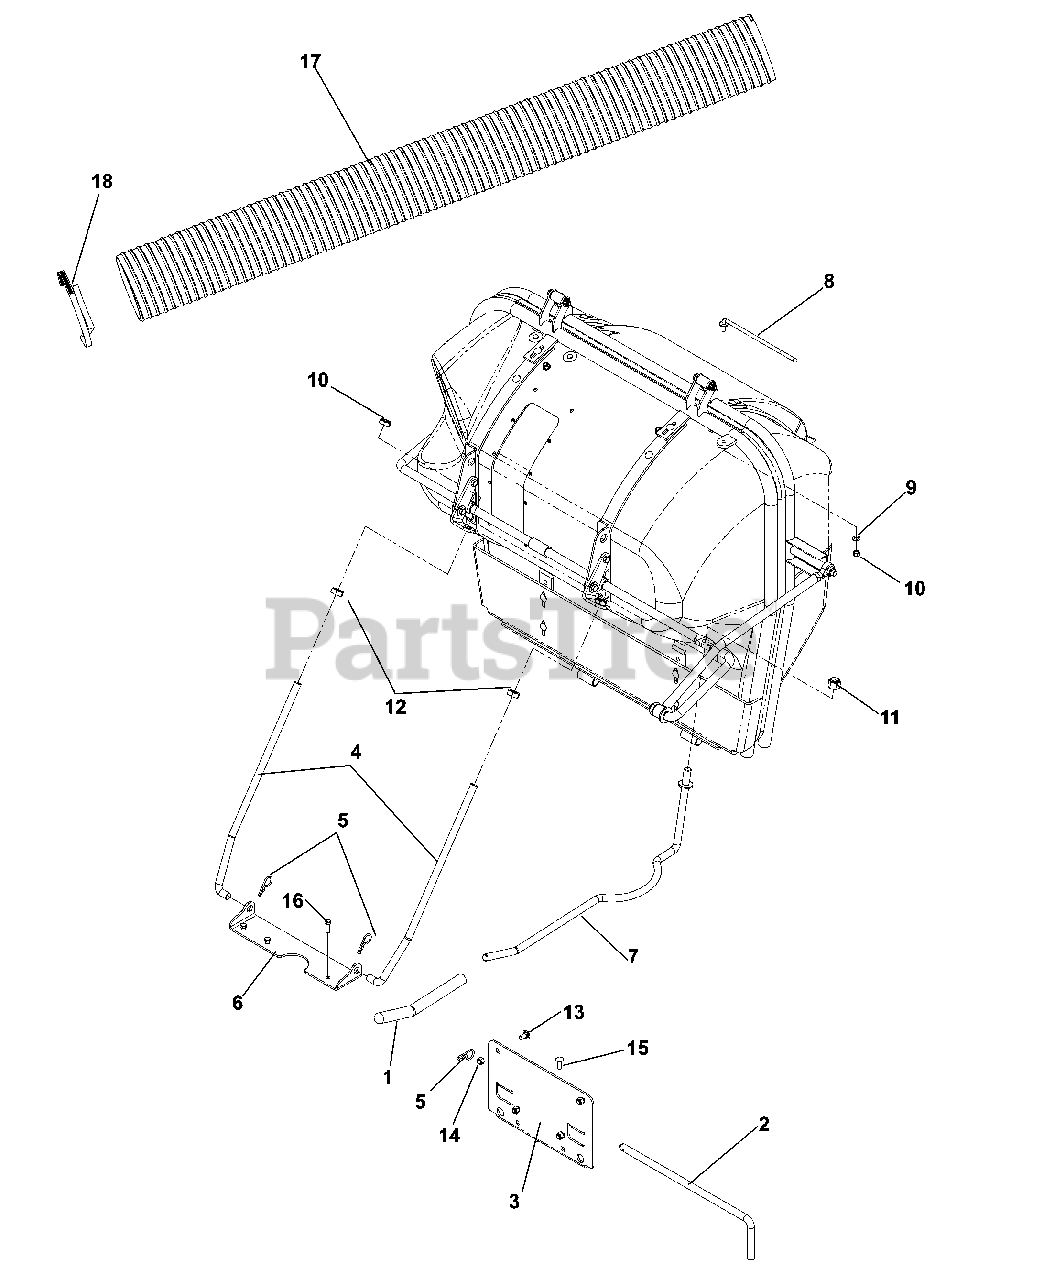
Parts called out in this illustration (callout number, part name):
1	BAR SLEEVE
2	HINGE PIN
3	BRACKET, MOUNT, LOWER
4	LINKAGE, SUPPORT
5	PIN, COTTER 1 3/4
6	BRACKET, SUPPORT, LINKAGE
7	LINKAGE, ARM, DUMP
8	LINKAGE.LATCH
9	FLAT WASHER 5/16 SAE
10	NUT 5/16 NYLOC
11	NUT 5/8-11 NYLOC
12	NUT JAM 5/8-11 HEX
13	RHSNB 3/8-16 X 3/4 GR5 ZD
14	NUT 3/8-16 NYLOC
15	RHSSNB 5/16C X 1.0
16	HCS 5/16C X 1
17	FLEX HOSE 6 X 60
18	HOSE CLAMP
